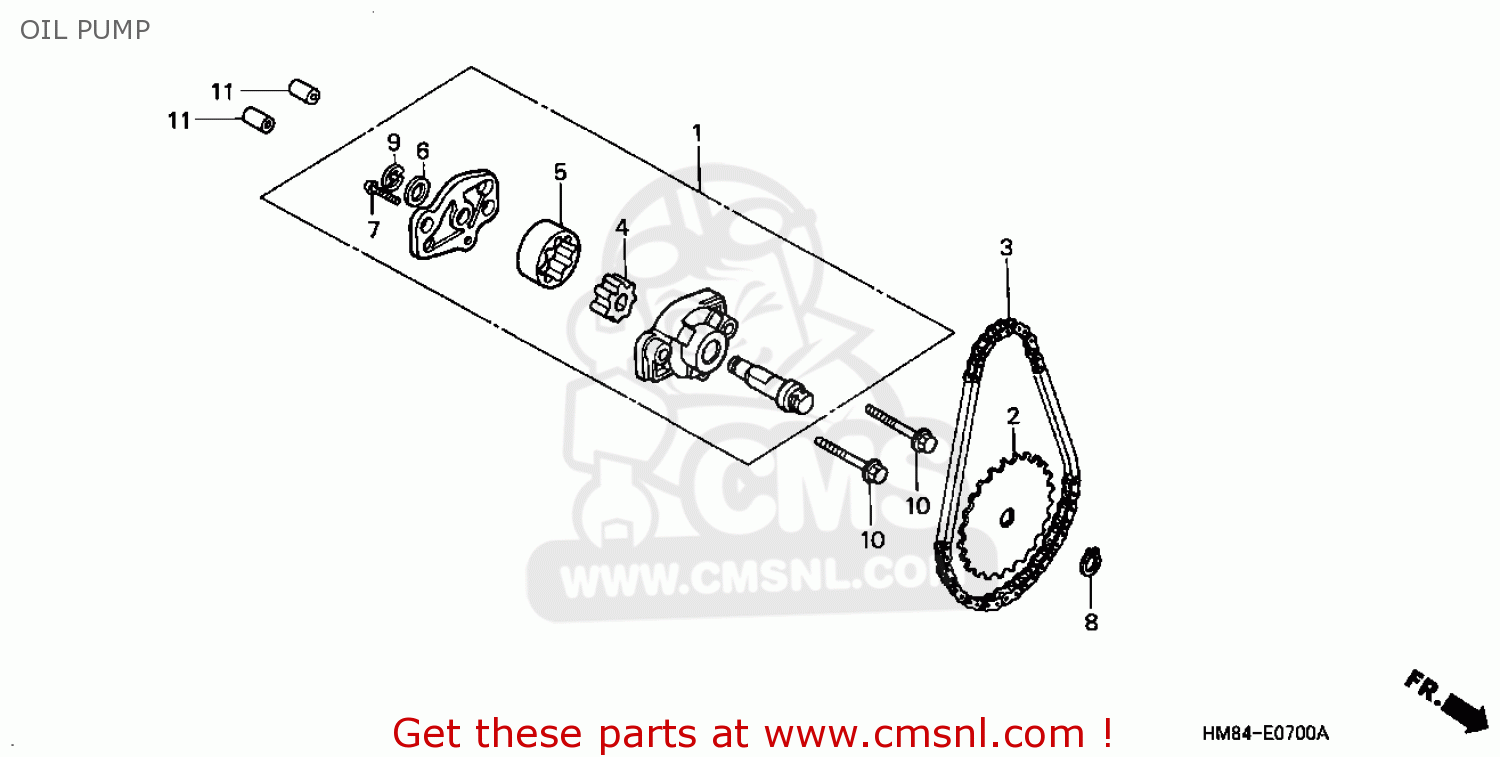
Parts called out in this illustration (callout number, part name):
1	OIL PUMP ASSY
2	SPRKT,OIL PUMP DR
3	CHAIN,OIL PUMP
4	ROTER OIL PUMP IN
5	ROTER OIL PUMP OU
6	WASHER,6.1MM
7	SCREW,PAN 3X12
8	CIRCLIP, 10M/M
9	E RING,5
10	BOLT,FLNAGE,6X35
